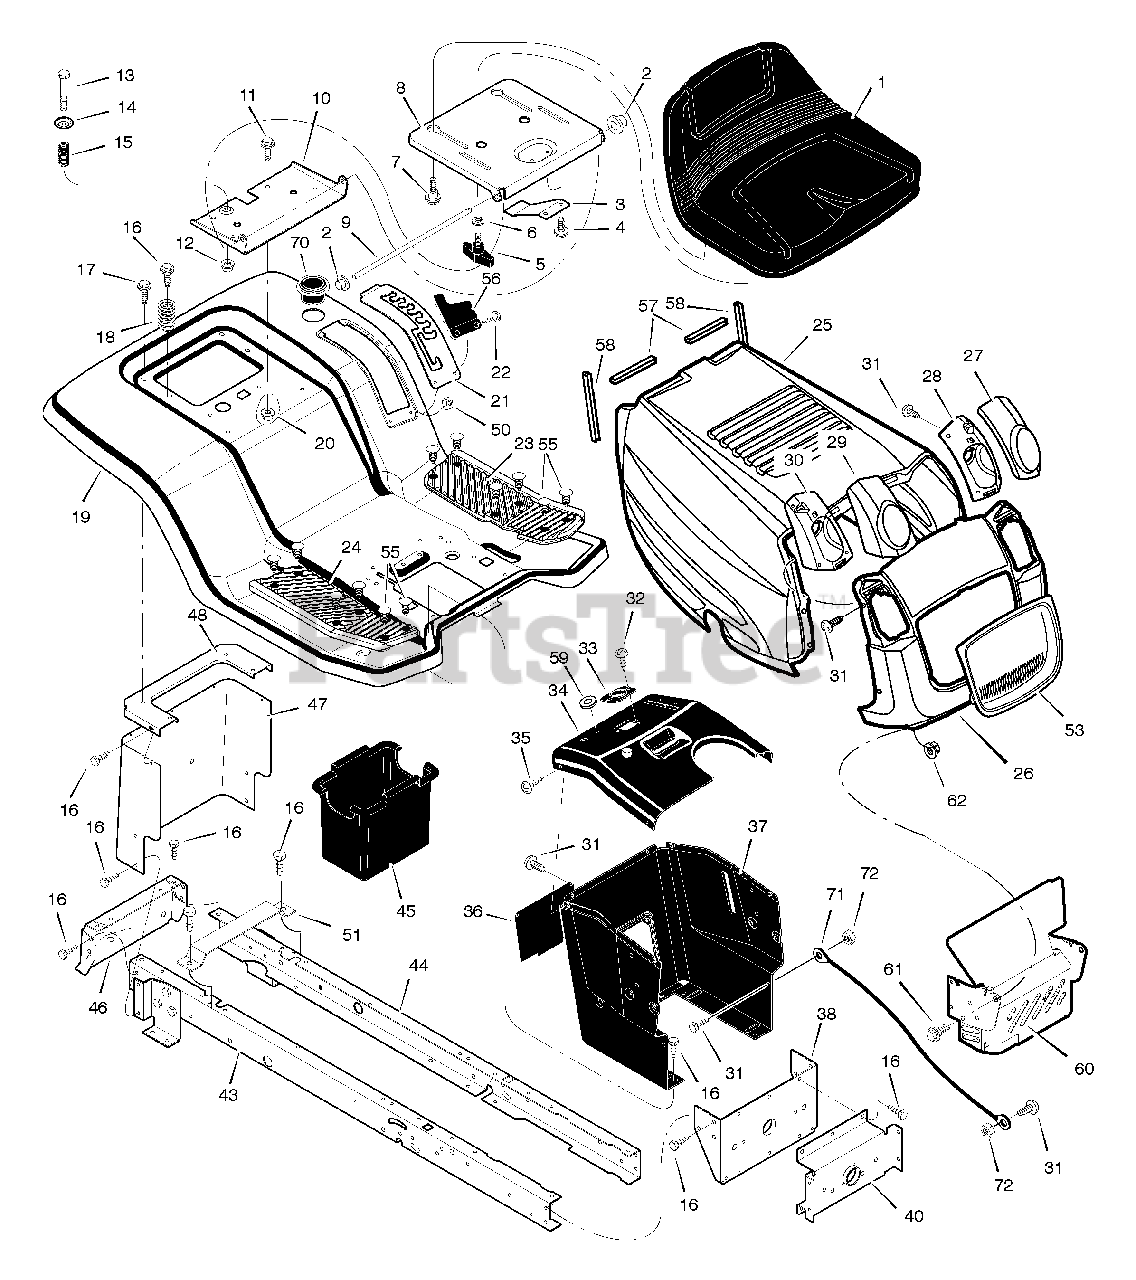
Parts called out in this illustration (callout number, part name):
2	Cap, Push 0n
5	Bolt, Wing
6	Washer
7	Bolt, Shoulder
8	Support, Seat
9	Rod, Pivot
10	Bracket, Pivot
11	Bolt
13	Bolt, Shoulder
15	Spring
19	Deck, Seat
20	Nut
21	Plate, Index
23	Mat, Left
24	Mat, Right
25	Hood
27	Lens, Left
28	Housing, Left Headlamp
29	Lens, Right
30	Housing, Right Headlamp
31	Screw
33	Bearing, Steering
34	Dash
36	Panel, Access
37	Support, Dash
38	Bracket, Rear Hanger
40	Axle, Hanger
43	Frame, Right
44	Frame, Left
45	Container, Battery
46	Plate, Hitch
47	Plate, Rear
48	Top, Rear Plate
51	Bracket, Battery Support
53	Insert, Grille
55	Fastener, Panel
56	Cover, Detent
57	Trim, Hood (3.75")
58	Trim, Hood (6.5")
59	Grommet, Parking Brake
60	Shield, Heat
61	Bolt, Shoulder
62	Locknut, Flange
70	Holder, Cup
